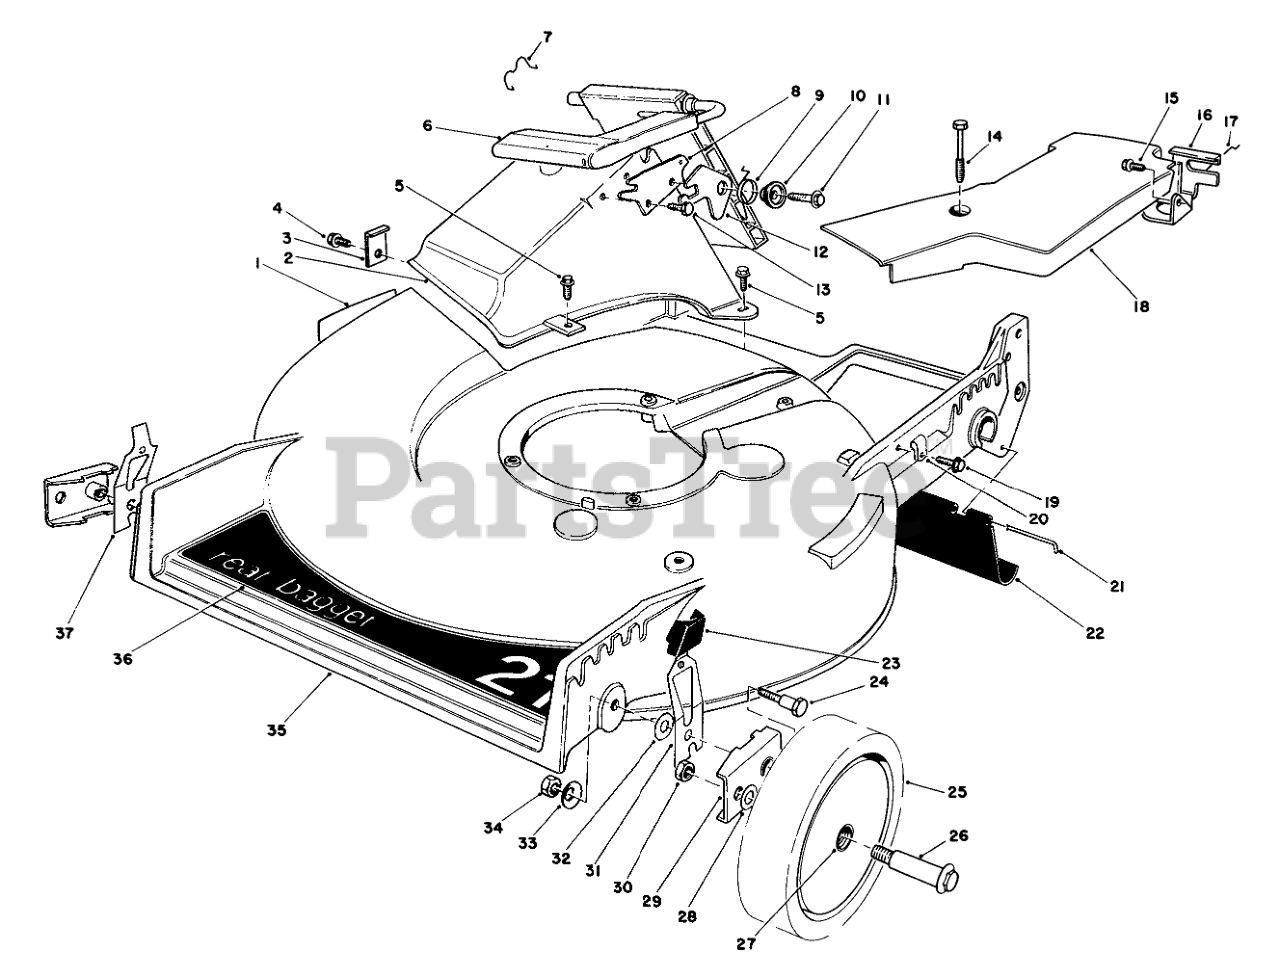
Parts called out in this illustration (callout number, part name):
1	DECAL-DANGER
2	Tunnel Discharge
3	TUNNEL CLIP
4	SCREW
5	SCREW-HWH
6	Discharge Door Assembly
7	DOOR RET SPRING
8	DOOR LATCH PLATE
9	TORSION SPRING
10	DOOR SPACER
11	SCREW-HWH
12	SAFETY LATCH
13	SCREW-PLASTITE
14	SCREW-HHFTF
15	SCREW-HWHTF
16	Bracket-Traction Adj.
17	RETAINER-CABLE
18	Cover-Belt
19	SCREW
20	CLAMP-CABLE
21	ROD-SHIELD
22	SHIELD-TRAILING
23	KNOB-ARM
24	PIVOT SCREW
25	Wheel & Tire Assembly (Incl. Ref. #27)
26	WHEEL BOLT
27	BUSHING
28	WASHER
29	HP PIVOT ARM ASM
30	NUT-LOCK
31	L. HP SPRING ARM ASM
32	WASHER-PIVOT
33	WASHER-BELLEVILLE
34	NUT-LOCK, NI
35	Housing (Incl. Ref. #1)
36	DECK DECAL
37	R HP SPRING ARM ASM
